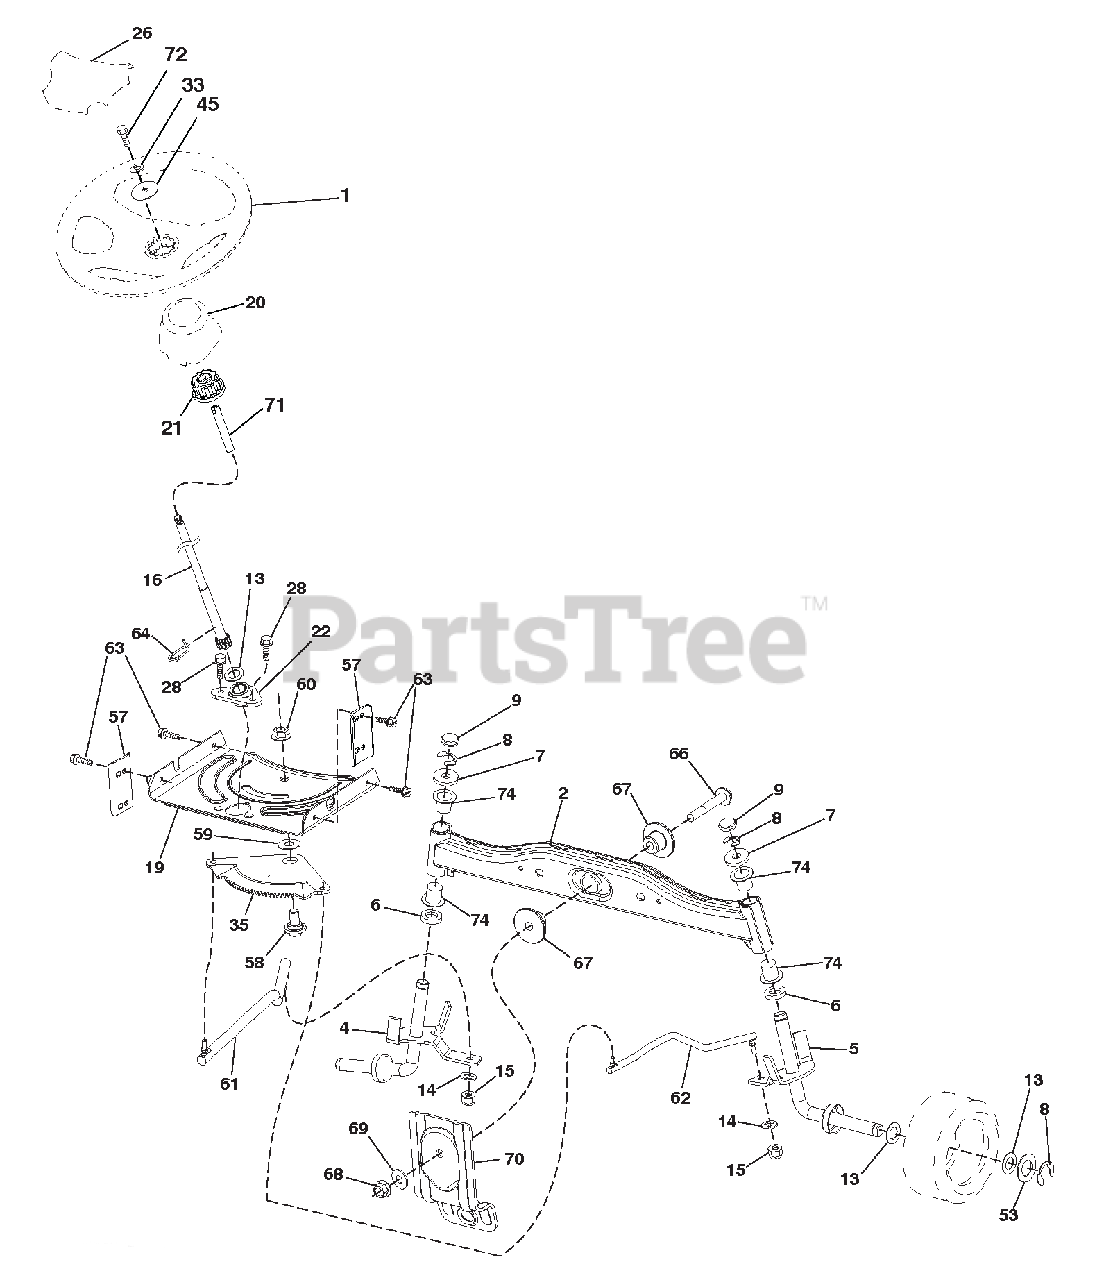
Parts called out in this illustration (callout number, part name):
1	WHEEL.STEERING.HARD RIM.BLACK
2	AXLE ASM.WELDED
4	SPINDLE.WELDED.LH.15"TEX
5	SPINDLE.WELDED.RH.15"TEX
6	WAHSER THRUST .75 X 1.230
7	WASHER.25/32 X 1-5/8 X 16GA.
8	RING.KLIP.#T5304-75
9	CAP.SPINDLE.FR.TOP.BLK.
13	WASHER.25/32 X 1 1/4 X 16 GA.
14	Washer, Lock 3/8
15	NUT.CROWNLOCK.3/8-24
16	SHAFT.STEER.3/4 TEX.NON-PLATED
19	PLATE.STEER.DDL.NLT/NGT
20	BOOT.STEERING
21	ADAPTER.WHEEL.STRG..760
22	STEERING SUPT.LOWER
26	CAP WHEEL STEERING HRS/SRS BLK
28	SCREW.HEXWSH THDR3/8-16X3/4.BL
33	Washer, Lock 5/16
35	GEAR SECTOR.PLATE.DDL.NLT/NGT
45	WASHER.11/32ID X2 3/8OD X 12GA
53	WASHER.HARDEN..793 X 1.637X060
57	BRACKET.UPSTOP.TEX
58	BOLT.SHOULDER.SECTOR.PIVOT.CFM
59	WASHER.THRUST.SECTOR.STEER.NLT
60	NUT.FLANGE LOCK.5/8-11
61	DRAGLINK.LH.BALLSTUD.DDL.
62	DRAGLINK.RH.BALLSTUD.DDL
63	SCREW.5/16-18X3/4.SMGML.TAP/BL
64	RETAINER.CLIP.SPRING.STEERING
66	BOLT.HEX.FGHD.7/16-14 X 3.SERR
67	BUSHING.PM.FRONT AXLE
68	NUT.LOCK.FLANGE.7/16-14.GR5
69	WASHER.1.5 X .505 X .118
70	BRACKET.DECK.SUSPENSION.FRONT
71	Extension Steering
72	Bolt 5/16-18 x 14 w/Patch
74	BEARING COL STRNG BLK
